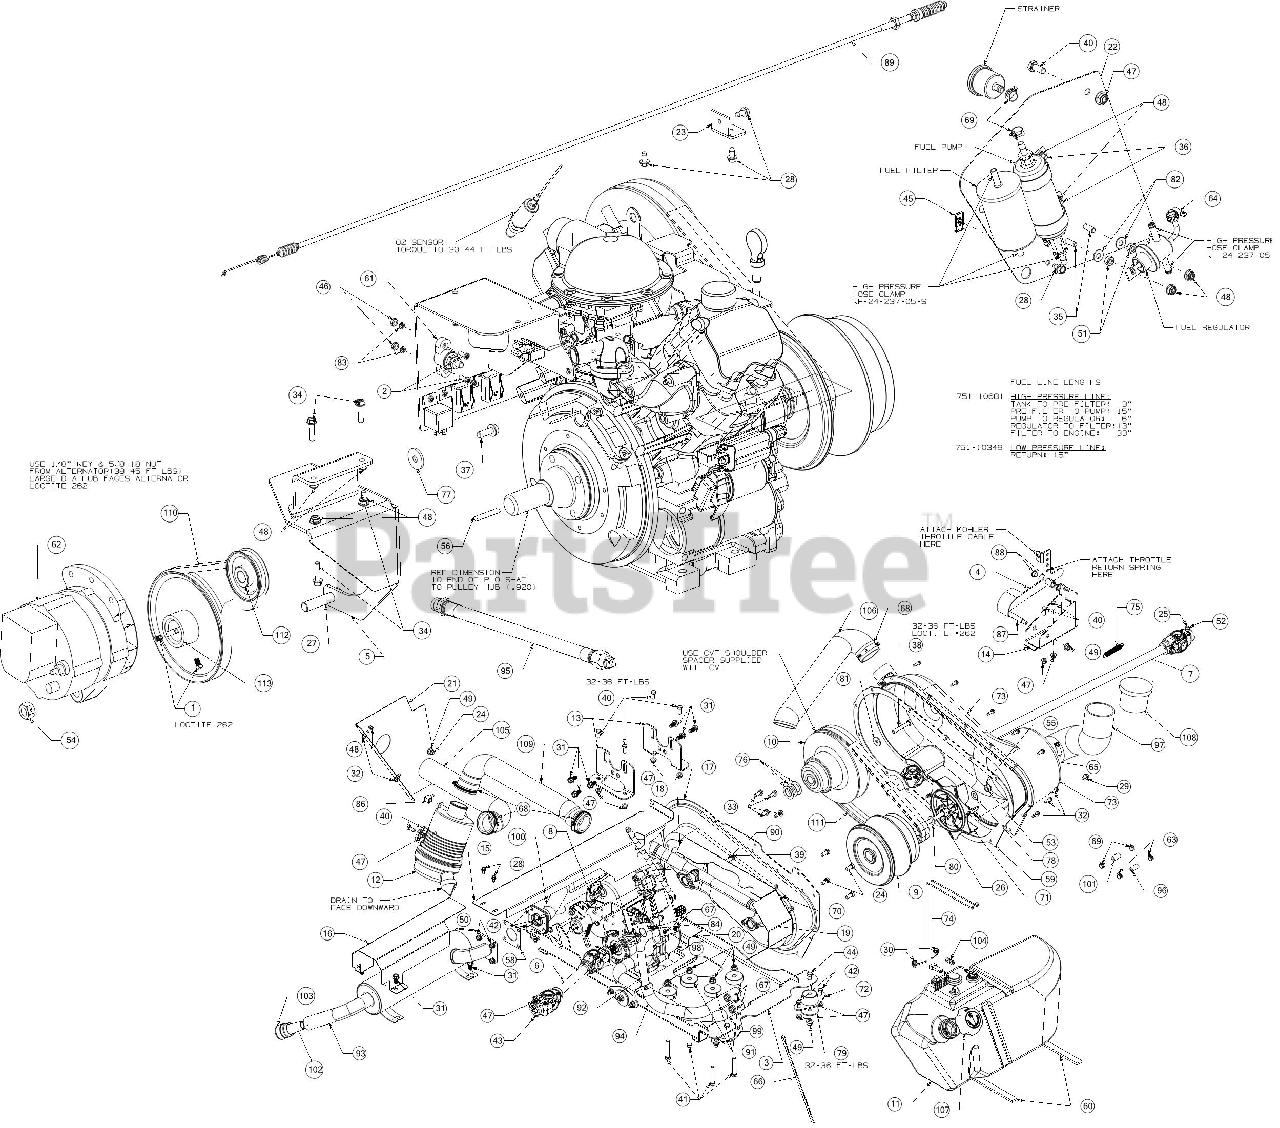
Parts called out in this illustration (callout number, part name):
1	SCREW-SET SQ 1/4-20
2	SCREW:10-32X.5
3	ENGINE TRAY ASSEMBLY
4	ACCELERATOR PEDAL ASSEMBLY
5	ALTERNATOR SUPPORT ASSEMBLY
6	SHAFT ASSEMBLY
7	SHAFT ASSEMBLY
8	TRANSFER CASE KIT
9	DRIVER CLUTCH ASSEMBLY
10	DRIVEN CLUTCH ASSEMBLY
11	FUEL TANK ASSEMBLY
12	AIRCLEANER FILTER ASSEMBLY
13	TRANSMISSION MOUNT BRACKET
14	ACCELERATOR PEDAL MOUNTING BRACKET
15	HEAT SHIELD COVER
16	HEAT SHIELD
18	ENGINE COVER
19	ENGINE COVER
20	HARNESS SHIELD
23	CABLE MOUNTING BRACKET
24	HEX SCREW 3/8-16 x .75
25	SCREW 5/16-18 x 1.875 GR5
26	SCREW 7/16-20 x 5.00 GR5
27	SCREW 1/2-13 x 2 GR5
28	SCREW 1/4-20 X.500
29	SCREW 5/16-12 x 1/2
30	SCREW 5/16-18 x .500
31	SCREW 3/8-16 x 3/4
32	SCREW 1/4-20 x .750
33	SCREW 5/16-18 x .875
34	SCREW 1/4-20 x 1.00
35	SCREW 1/4-20X.75
36	SCREW 1/4-20 x .625
37	SCREW 5/16-18 x .875 GR5
38	SCREW 3/8-24 x 2.50 GR8
39	SCREW 1/4-20 X1.625
40	SCREW 5/16-18 x .75 GR5
41	SCREW 3/8-16 x 2.25 GR5
42	SCREW 5/16-18 x .875 GR5
43	SCREW 5/16-18 x 2.0 GR5
44	SCREW 3/8-16 x 2.0 GR5
45	SPEED NUT
46	HEX NUT 10-32
47	FLANGE LOCK NUT 5/16-18
48	FLANGE LOCK NUT
50	HEX FLANGE NUT
52	HEX NUT
53	HEX NUT
54	HEX NUT CTR LK 1/2-13
55	COTTER PIN-3/32
56	SQUARE KEY 1/4 x 1.50
58	ENGINE GASKET
59	CVT COVER SEAL
60	FOAM TAPE .75" WIDE x .25" THICK
61	ELECTRIC POWER DISTRIBUTION POST
62	ALTERNATOR
63	HOSE CLAMP 1/20
64	HOSE CLAMP
65	HOSE CLAMP
66	CABLE TIE 18"
67	HOSE CLAMP
68	HOSE CLAMP 2-3"
69	HOSE CLAMP
70	POP RIVET .125#42
72	ENGINE NEOPRENE MOUNT
74	FUEL TANK WIRE
75	EXTENSION SPRING
76	FLAT WASHER
77	FLAT WASHER
78	FLAT WASHER .510 x 1.00 x .060
79	FLAT WASHER .380x2.000x.120
80	FLAT WASHER
81	BELL WASHER
82	FLAT WASHER
83	LOCK WASHER
84	1/8 NPT COOLANT DRAIN PETCOCK
86	90 DEGREE FITTING
87	SHOULDER SCREW .50 x 2.23 3/8-16
88	NYLINER BEARING
89	THROTTLE CABLE
91	ENGINE SPACER
92	RADIATOR TUBE
93	MUFFLER (CAT/KOHLER)
94	RADIATOR HOSE
95	OIL DRAIN HOSE
96	FUEL HOSE LOW PERMEATION
97	CVT INTAKE TUBE
98	RADIATOR HOSE (TOP)
99	RADIATOR HOSE (LOWER)
100	EXHAUST PIPE (KOHLER) (EFI)
101	FUEL HOSE LINE 5/16 ID
102	SCREEN ARRESTOR 1.50" DIA
103	CLAMP ARRESTOR 1.50" DIA
104	FUEL HOSE LO PERMEATION
105	AIR INLET HOSE
106	CVT EXHAUST HOSE
107	FUEL CAP W/TETHER
108	CVT INLET FILTER
109	AIR INTAKE HOSE
110	BELT 3/8 x 26.6
112	ALTERNATOR PULLEY
113	PULLEY-6.0 OD 1.12
